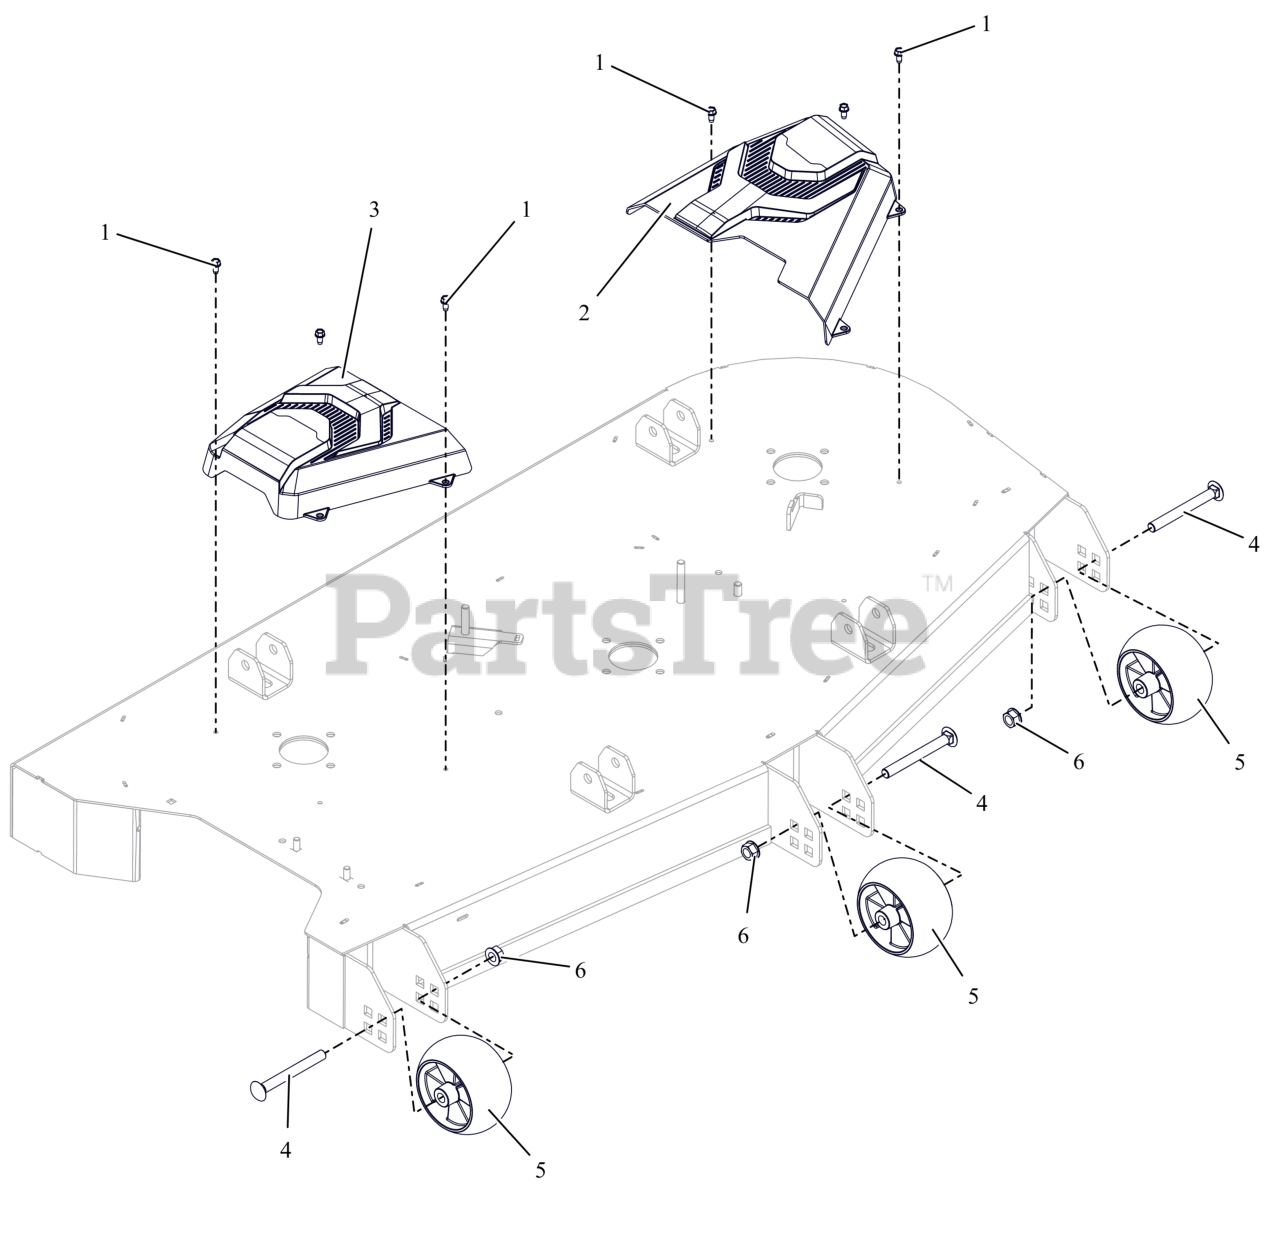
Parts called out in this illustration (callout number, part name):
1	SCR-TAP .25-20X.50 HWH ZCC
2	COVER- BELT LH
3	COVER- BELT RH
4	BLT-RHNS .50-13X4.50 G5 ZCC NS
5	WHEEL, ANTI SCALP - 5X3 CTR W/RIBS
6	NUT-LK-CTR-FLG .500-13 GG ZCC
